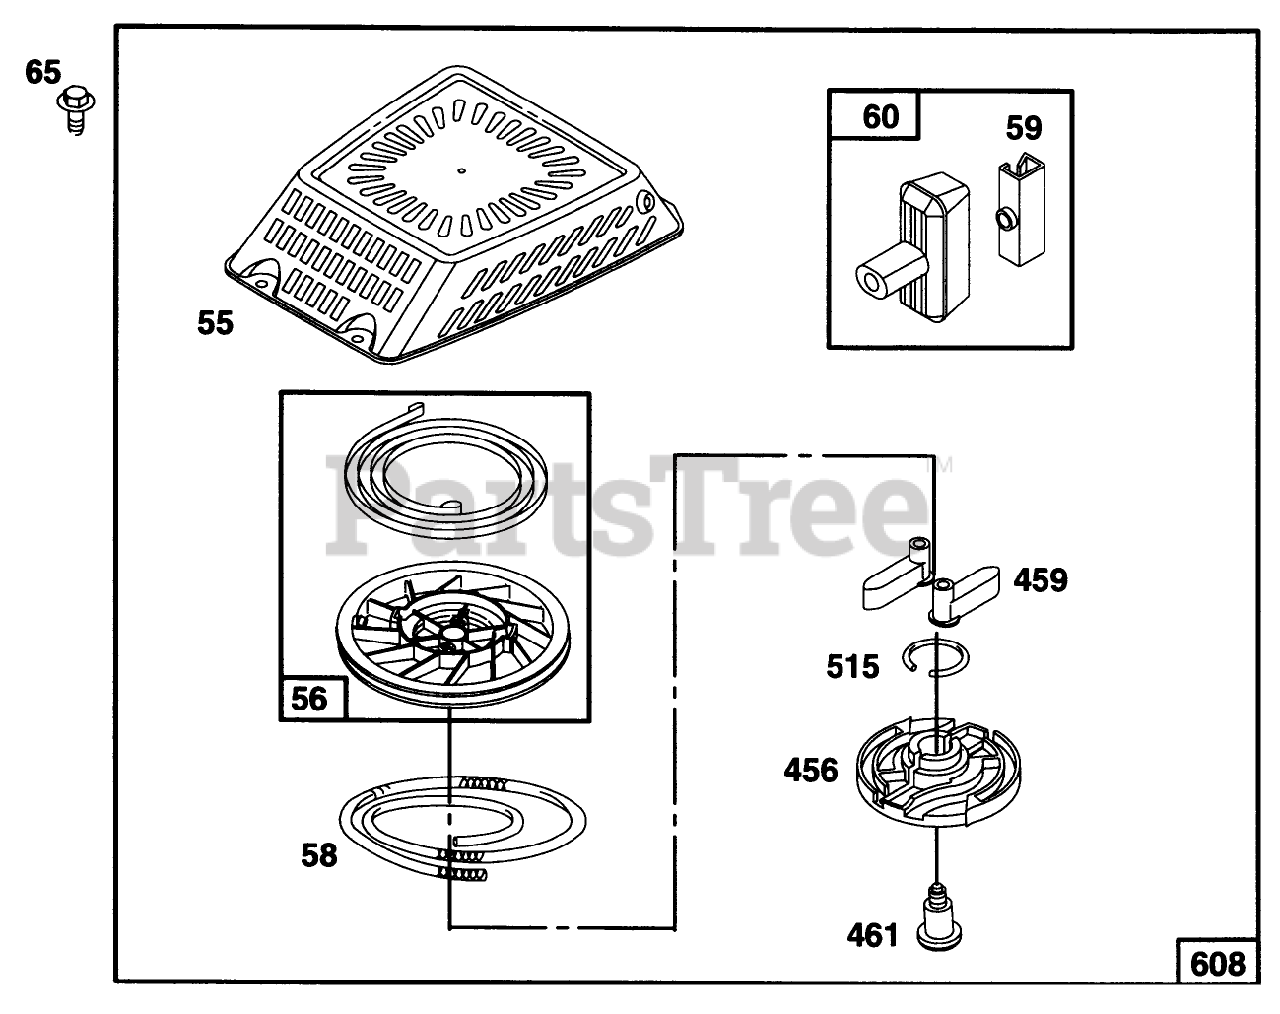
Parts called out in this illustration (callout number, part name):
56	PULLEY-STARTER, REWIND
58	ROPE-STARTER
59	INSERT-HANDLE, REWIND
456	RETAINER-STARTER, REWIND
459	PAWL-STARTER
515	SPRING-TORSION
